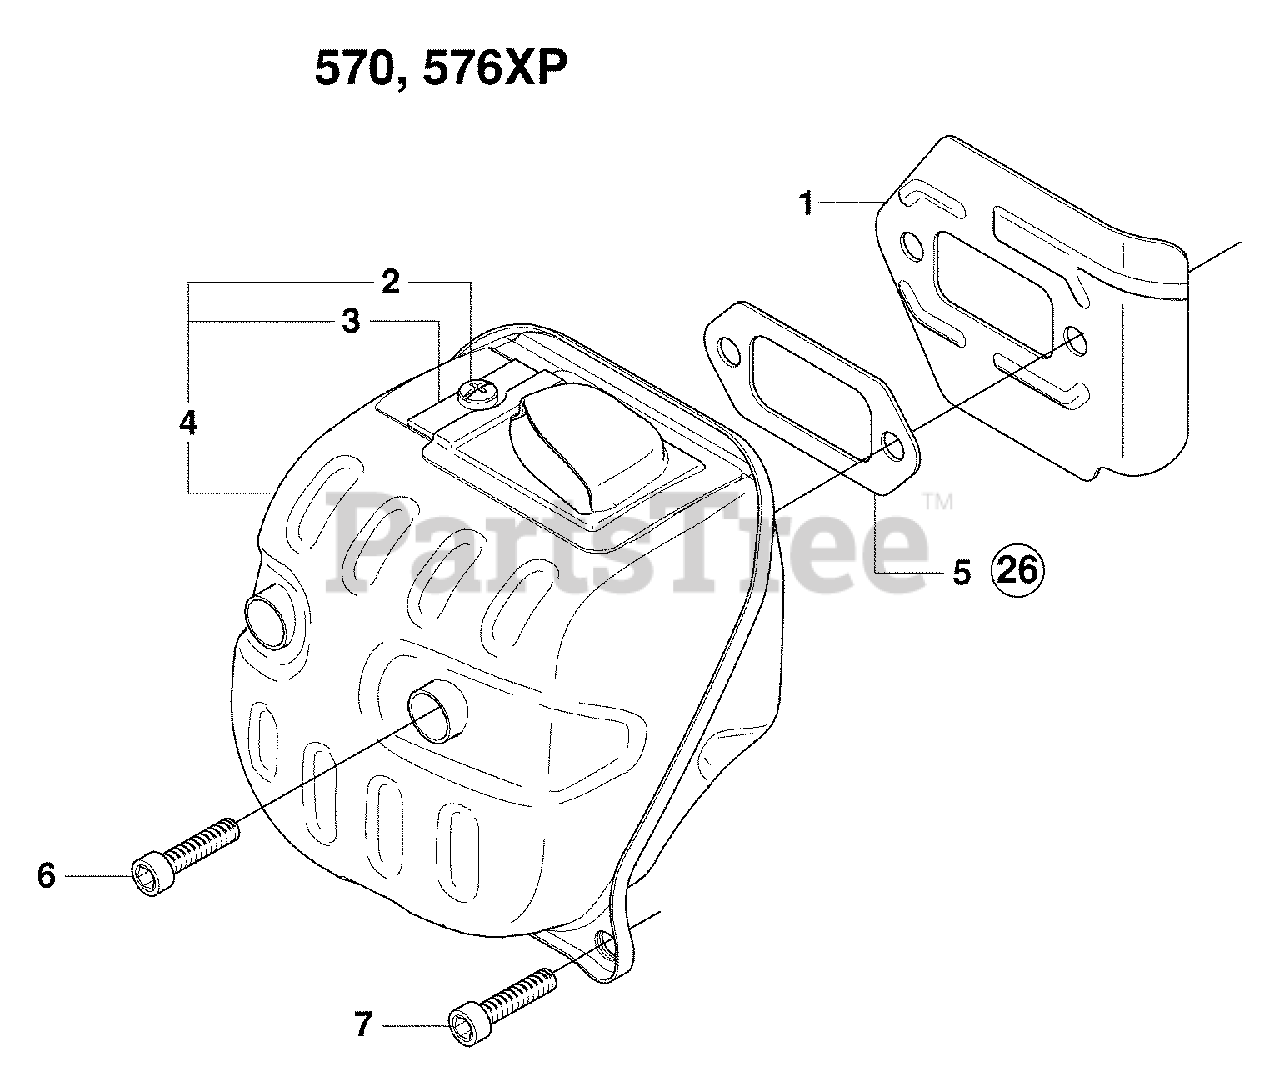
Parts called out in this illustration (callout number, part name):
4	Muffler Assembly
5	Muffler Gasket
6	Screw, M6 X 20
26	Gasket Set
26	Gasket Kit
